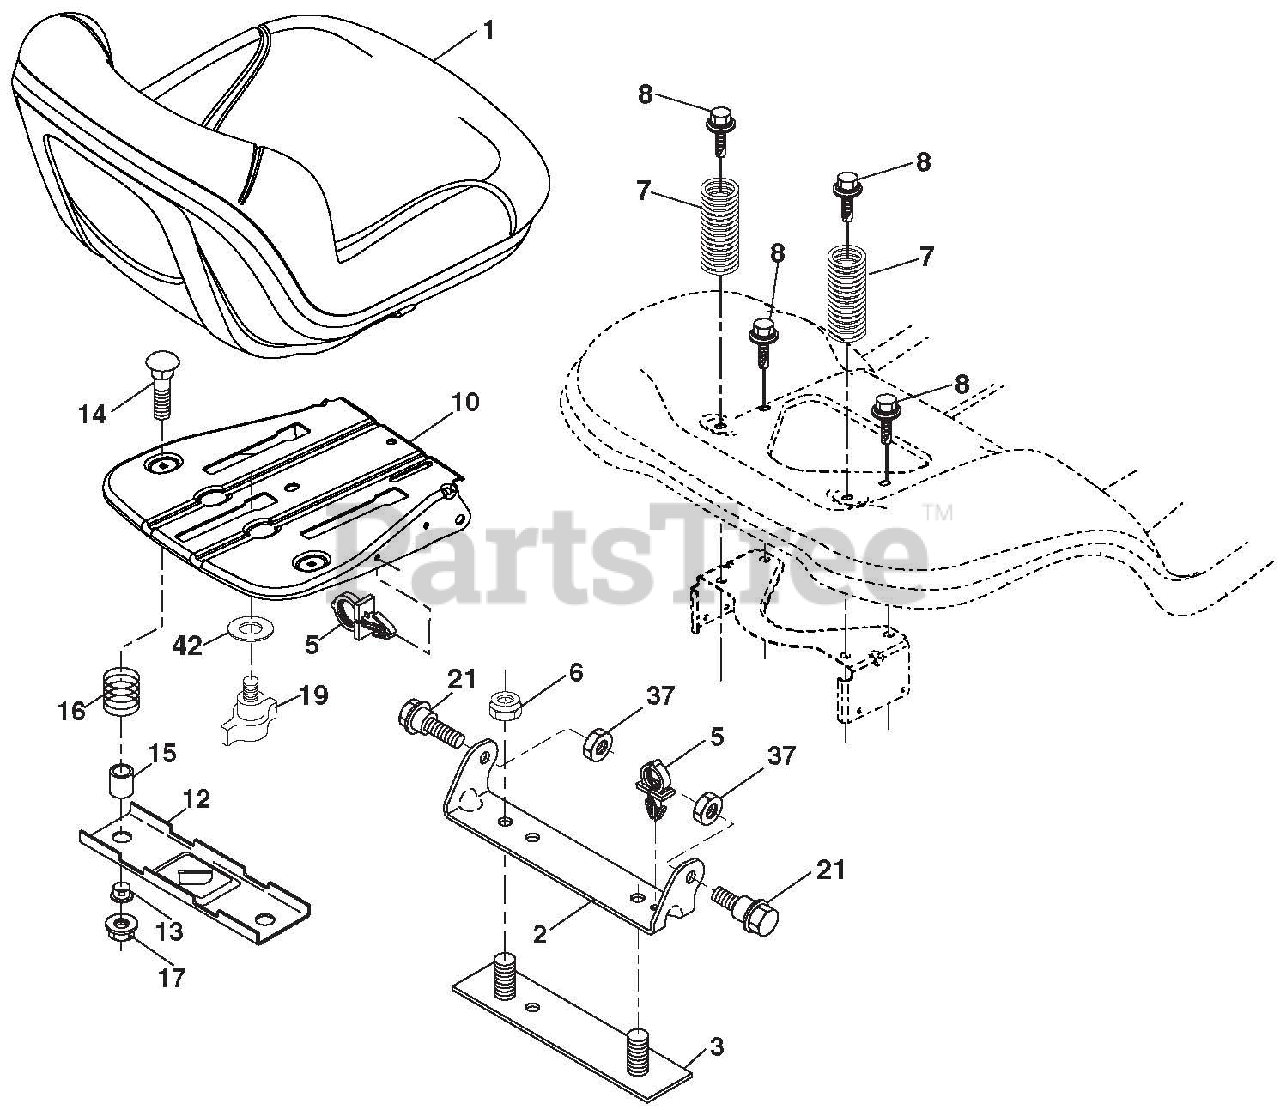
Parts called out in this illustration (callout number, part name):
1	SEAT.TA110.BLACK.ARIENS
2	BRACKET.PIVOT.FENDER.2002
3	STRAP ASM.FENDER.94
5	CLIP.PUSH-IN.HINGED
6	Locknut, Washer Insert 3/8-16
7	SPRING.SEAT.CPRSN.2.250.BLK.ZI
8	BOLT.5/16-18UNCX3/4 W/SEMS.BLK
10	PAN, SEAT
12	BRACKET.MNT.OPC.SW.SEAT.TEX LT
13	BUSHING.SNAP.BLK.NYL..50 ID.
14	BOLT.RDHD.SHT.NK.1/4-20X1-1/2
15	SPACER.SPLIT..28X.96.YEL.ZINC
16	SPRING.CPRSN.PLATE.SW.1.310.GA
17	NUT.LOCK.1/4 LGE.FLG.GR.5.ZINC
19	KNOB.SEAT ADJ.3/8-16"TEX
21	BOLT.SHLD.5/16-18 UNC-2A.BLK D
37	Locknut, Washer Insert 5/16-18
42	WASHER.CUP.SEAT.TEX LT
